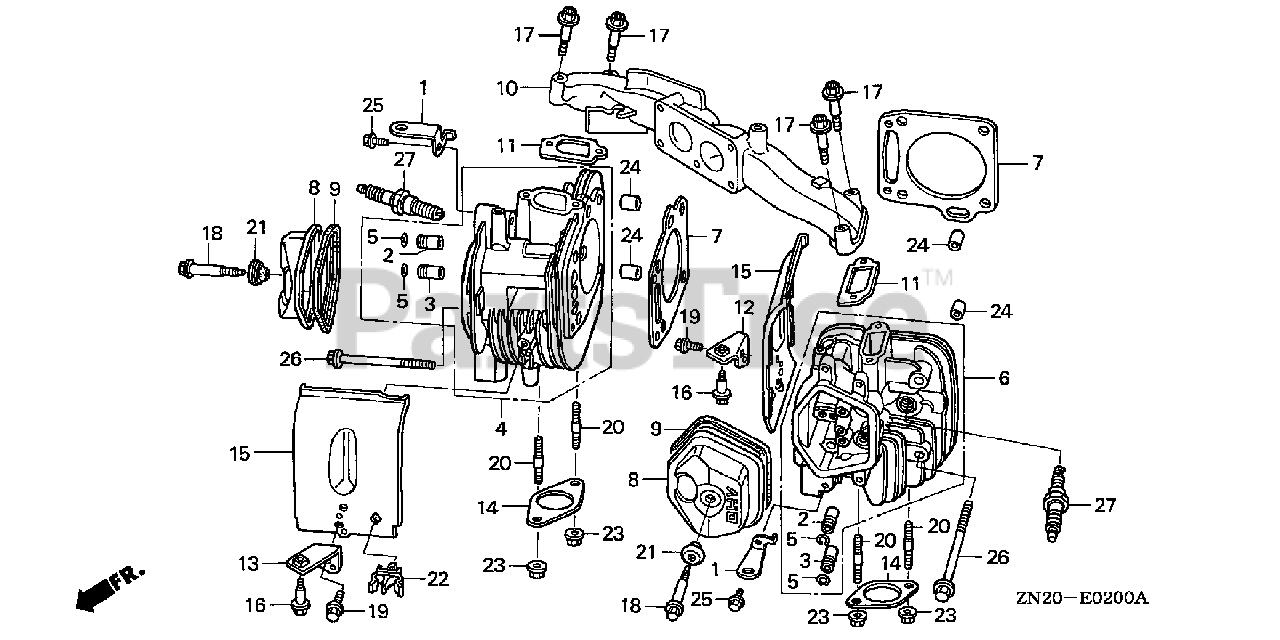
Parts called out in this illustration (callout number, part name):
1	HANGER, ENGINE
2	GUIDE, VALVE (OS)
3	GUIDE, EX. VALVE (OS)
4	CYLINDER HEAD (#1)
5	CLIP, VALVE GUIDE
6	CYLINDER HEAD (#2)
7	GASKET, CYLINDER HEAD
8	COVER, HEAD
9	GASKET, CYLINDER HEAD COVER
10	MANIFOLD, IN.
11	GASKET, IN. MANIFOLD
12	BRACKET, R. AIR CLEANER
13	BRACKET, L. AIR CLEANER
14	GASKET, EX. PIPE
14	GASKET, EX. PIPE (WACKER)
15	SHROUD, HEAD
16	BOLT, FLANGE (6MM)
17	BOLT, SOCKET (8X45)
18	BOLT, HEAD COVER
19	BOLT, FLANGE (6X14)
20	BOLT, STUD (8X22)
21	WASHER, HEAD COVER
22	CLIP, FUEL TUBE
23	NUT, FLANGE (8MM)
24	PIN A, DOWEL (12X20)
25	BOLT, FLANGE (8X20)
26	BOLT, FLANGE (10X80)
27	SPARK PLUG (BPR2ES) (NGK)
27	SPARK PLUG (J14CR-U)
27	SPARK PLUG (ZGR4A) (NGK)
27	SPARK PLUG (J16CR-U)
27	SPARK PLUG (ZGR5A) (NGK)
